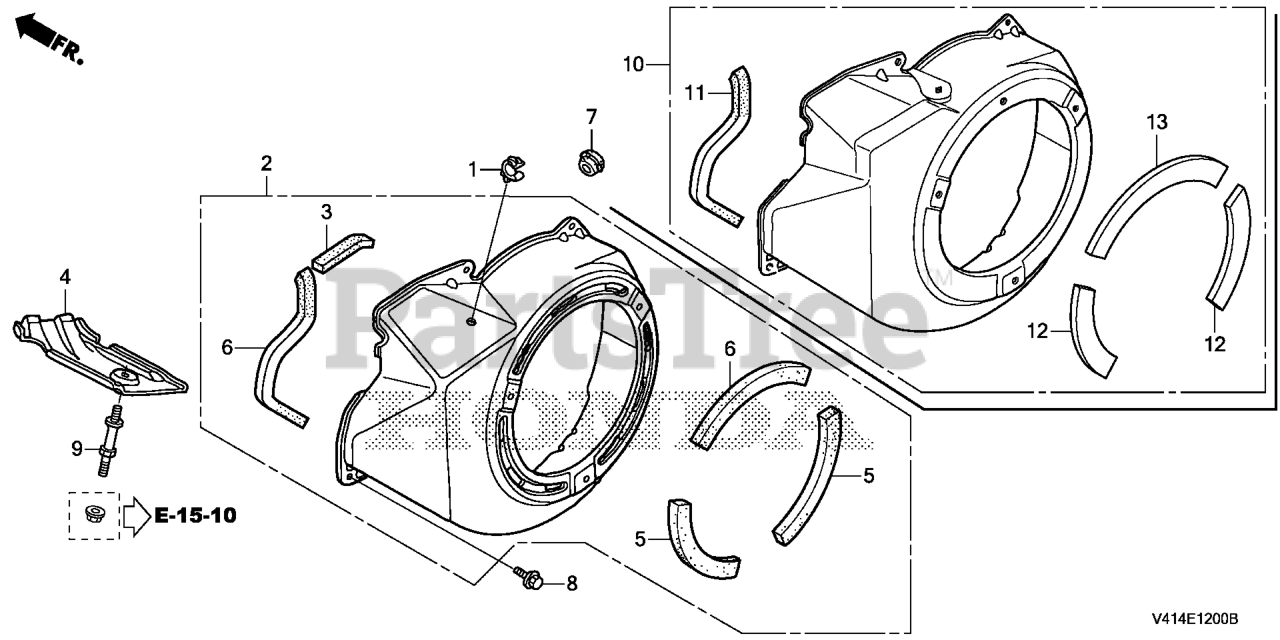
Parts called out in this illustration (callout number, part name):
1	CLIP, TUBE
7	GROMMET, DRAIN HOLE
8	BOLT, FLANGE (6X12) (CT200)
9	BOLT, SHROUD (LOWER)
10	COVER, FAN *R280* (POWER RED)
11	SEAL, RECOIL
12	SEAL, RECOIL
13	SEAL, RECOIL
